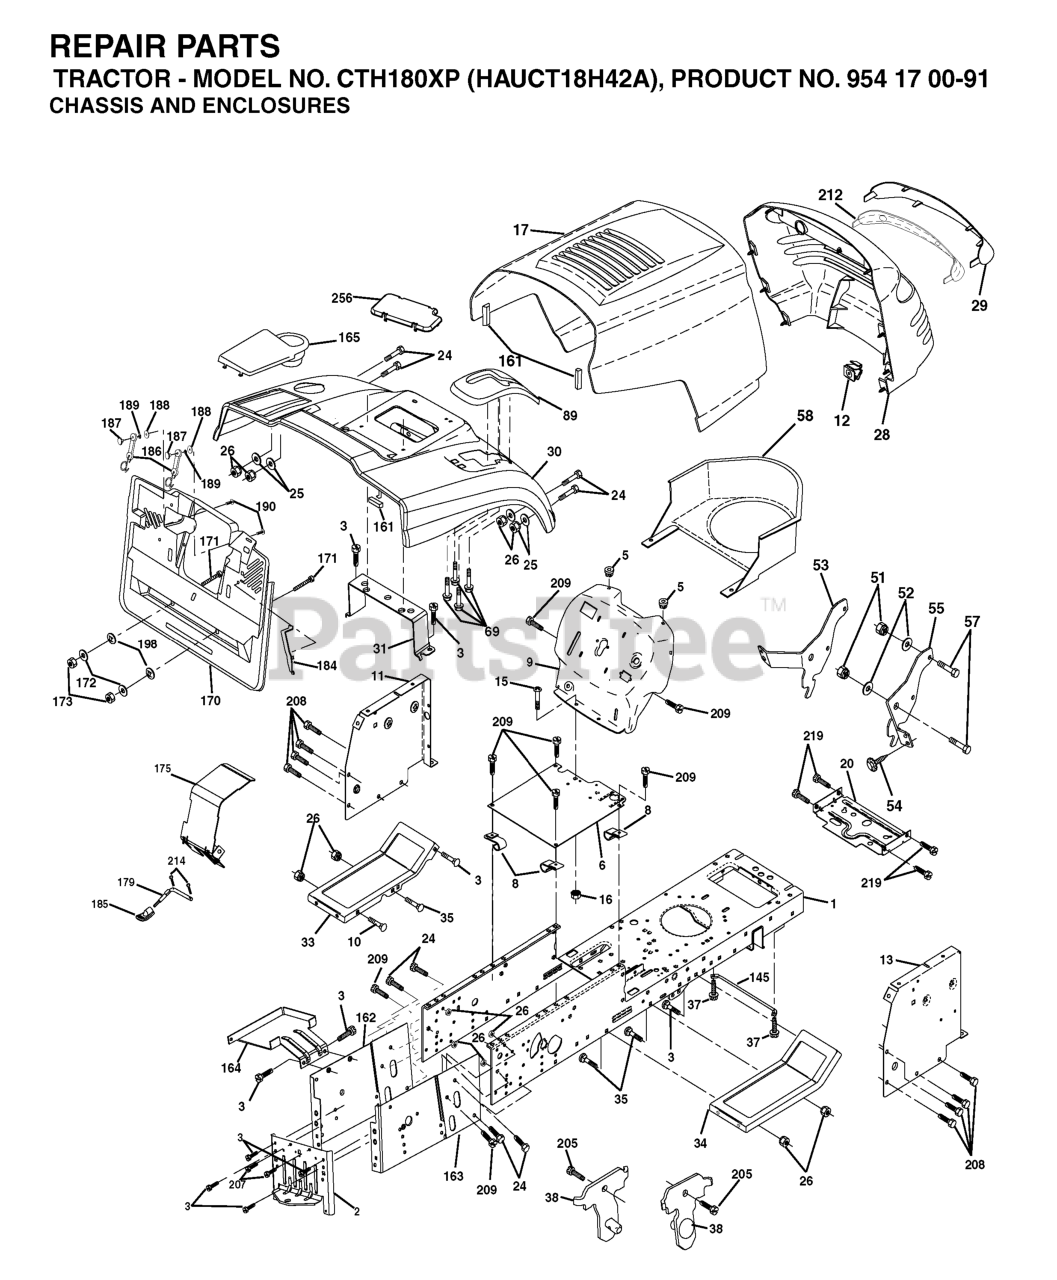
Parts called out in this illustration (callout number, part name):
2	DRAWBAR
3	SCREW 3/8-16X3/4
5	BUMPER.RUBBER.HOOD
6	SADDLE FLAT
8	CLIP,INSULATOR
10	BOLT D
11	PANEL.DASH.LH.LTX
13	PANEL ASM, DASH RH
15	Screw, Machine, Truss Head 5/16-18 UNC x 3/4
16	NUT
17	HOOD ASM.
20	PLATE MTG.BATTERY/FUEL TANK
25	WASHER
26	NUT
28	GRILLE/LENS ASM
29	LENS
31	BRACKET SUPPORT FENDER
33	FOOTREST PNT LH
34	FOOTREST PNT RH
37	Screw 5/16-18 x 1/2 Hex, Self Tapping 5/16-18 x 1/2
38	BRACKET ASM PIVOT MOWER REAR
51	LOCKNUT.NYLOC.1/4-20
53	BRACKET.GRILLE.LH
54	SCREW.HEX.WS.HD.8-18 X 7/8
57	BOLT
58	DUCT, INTAKE AIR
69	SCREW.HI-LO.CONSOLE
71	NUT.CROWNLOCK.1/4
89	COVER.BATTERY.CRD.GREY
145	ROD PIVOT CHASSIS/HOOD
161	EXTRUSION BUMPER (3 2) (2 2)
162	BRACKET
163	BRACKET EXTEN CHASSIS RH CRD
165	RP.COVER.BATTERY.CRD.GREY
172	WASHER
184	BRACKET.ACTUATOR.BAGGER.SRD
186	LATCH ASSY
187	WELDNUT
189	LOCKWASHER #10
190	SCREW
207	SCREW, 5/16-18 X 1/2
208	SCREW 3/8-16X1/2
209	SCREW, 3/8-16X3/4
212	REPL BY 532 1745-03
214	RETAINER M
219	SCREW
256	COVER FENDER CRD
